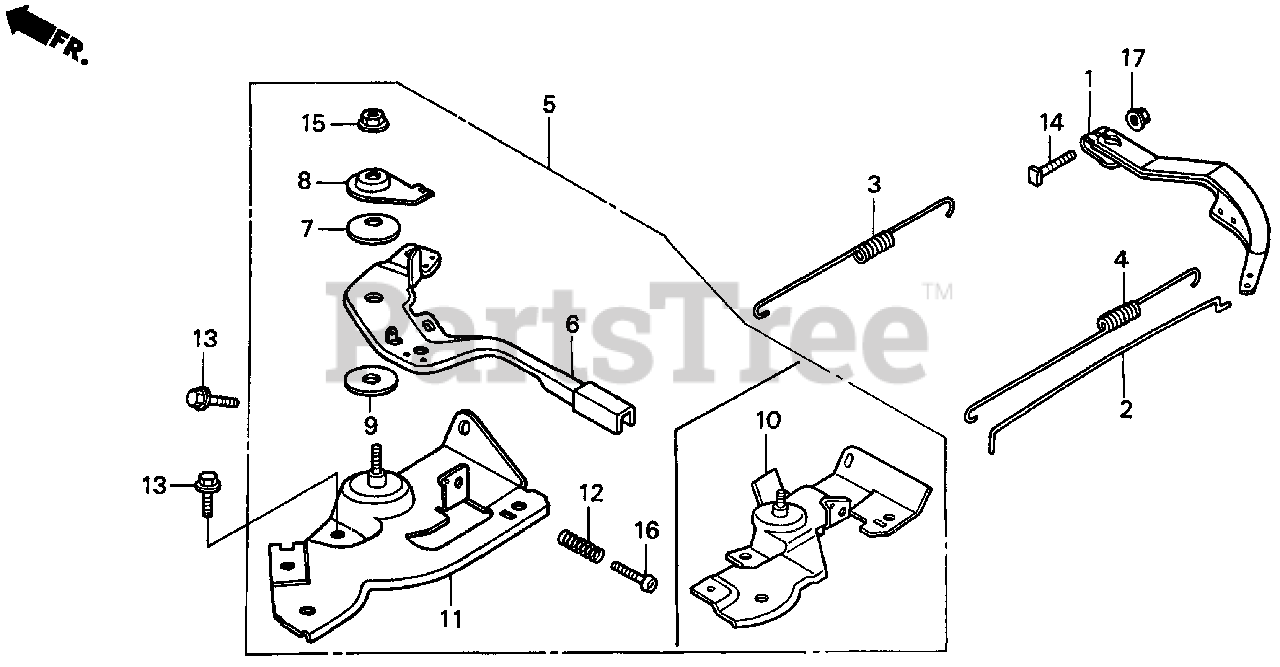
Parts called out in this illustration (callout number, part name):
1	ARM, GOVERNOR
2	ROD, GOVERNOR
3	SPRING, GOVERNOR
4	SPRING, THROTTLE RETURN
5	CONTROL ASSY.
6	LEVER, CONTROL
7	SPRING, LEVER
8	WASHER, CONTROL LEVER
9	SPACER, CONTROL LEVER
10	BASE, CONTROL
12	SPRING, CONTROL ADJUSTING
13	BOLT, FLANGE (6X12) (CT200)
14	BOLT, GOVERNOR ARM
15	NUT, SELF-LOCK (6MM)
16	SCREW, PAN (5X20)
17	NUT, FLANGE (6MM)
